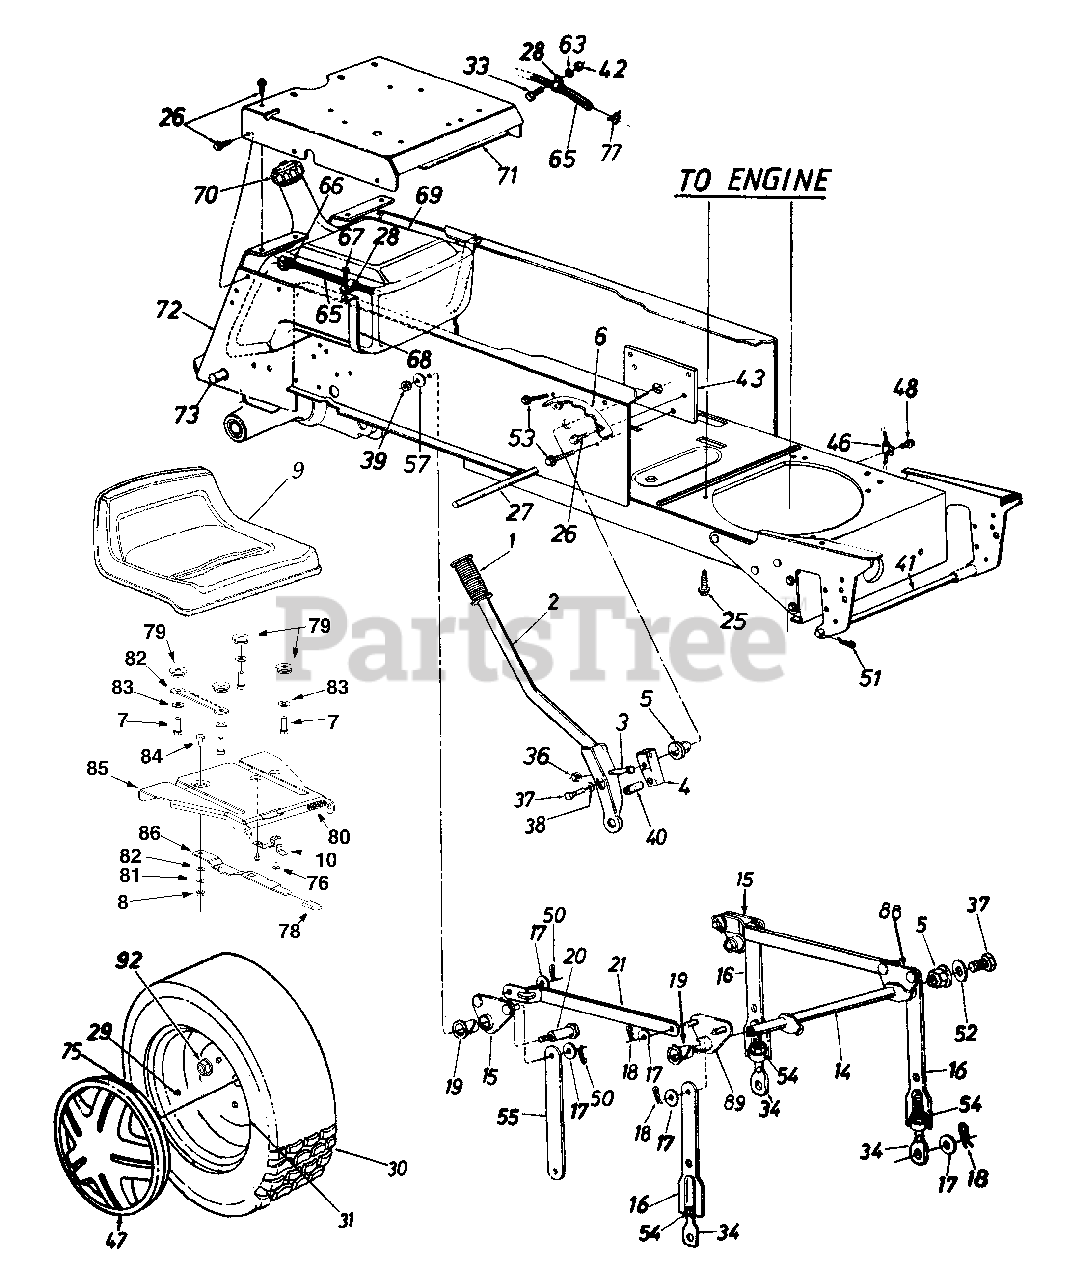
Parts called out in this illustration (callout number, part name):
1	Grip
2	Lift Handle Ass'y.
3	Hex Bolt 5/16-18 x 1.5" Lg.
4	Lift Shaft Drive
5	Plastic Hex Brg. 5/8" I.D.
8	Hex Flanged L-Nut 1/4-20 Thd.
9	Seat
10	Seat Stop
14	Lift Shaft Ass'y.
15	Lift Pivot Brkt. Ass'y.
17	Fl-Wash. 1/2" I.D. x 1.00" O.D. x .090"
18	Hairpin Cotter
19	Flanged Brg. 5/8" I.D.
20	Shld. Bolt 5/8" Dia. x .96" Lg. 3/8-16
26	Hex Thd. Rolling Scr. 5/16-18 x .75"
27	Running Board Rod
28	Clamp
29	Air Valve
33	Hex Bolt 1/4-20 x .62" Lg.
34	Eye Bolt Adj. Link 1/2-13 Thd.
36	Hex Cent. L-Nut 5/16-18 Thd.
37	Hex Bolt 5/16-24 x .75" Lg. (Gr. 5)
39	Hex Top L-Nut 3/8-16 Thd.
40	Compression Spring
41	Deck Connecting Rod
42	Hex Sems Nut 1/4-20 Thd.
47	Spoked Hub Cap (Yellow-Opt.)
48	Hex Wash. Hd. TT-Tap Scr.
50	Cotter Pin .09 Dia. x 1.0" Lg.
51	Int. Cotter Pin
52	Flat Wash. .34" I.D. x 1.12" O.D.
53	Hex Wash. Hd. AB-Tap Scr.
54	Hex Nut 1/2-13 Thd.
57	Bell-Wash. .4" I.D. x 1.13" O.D.
63	L-Wash. 1/4" I.D.
65	Fuel Line 46" Lg.
66	Hose Clamp
67	Hex AB-Tap Scr. 1/4 x .62" Lg.
68	Fuel Tank Strap
69	Gas Tank
70	Gas Gauge
71	Seat Plate
75	Spring Clip
76	Hex Wash. Hd. Tap Scr.
77	Hose Clamp
78	Seat Adjustable Grip
79	Spacer
80	Compression Spring
81	Spring Wash. .265" I.D.
82	Fl-Wash. .344" I.D.
83	Fl-Wash. .406" I.D.
84	Shld. Bolt .34" x 1/4-20 Thd.
88	Lift Pivot Brkt.-L.H.
89	Lift Pivot Brkt.-R.H.
92	Lug Nut 7/16-14 Thd.
